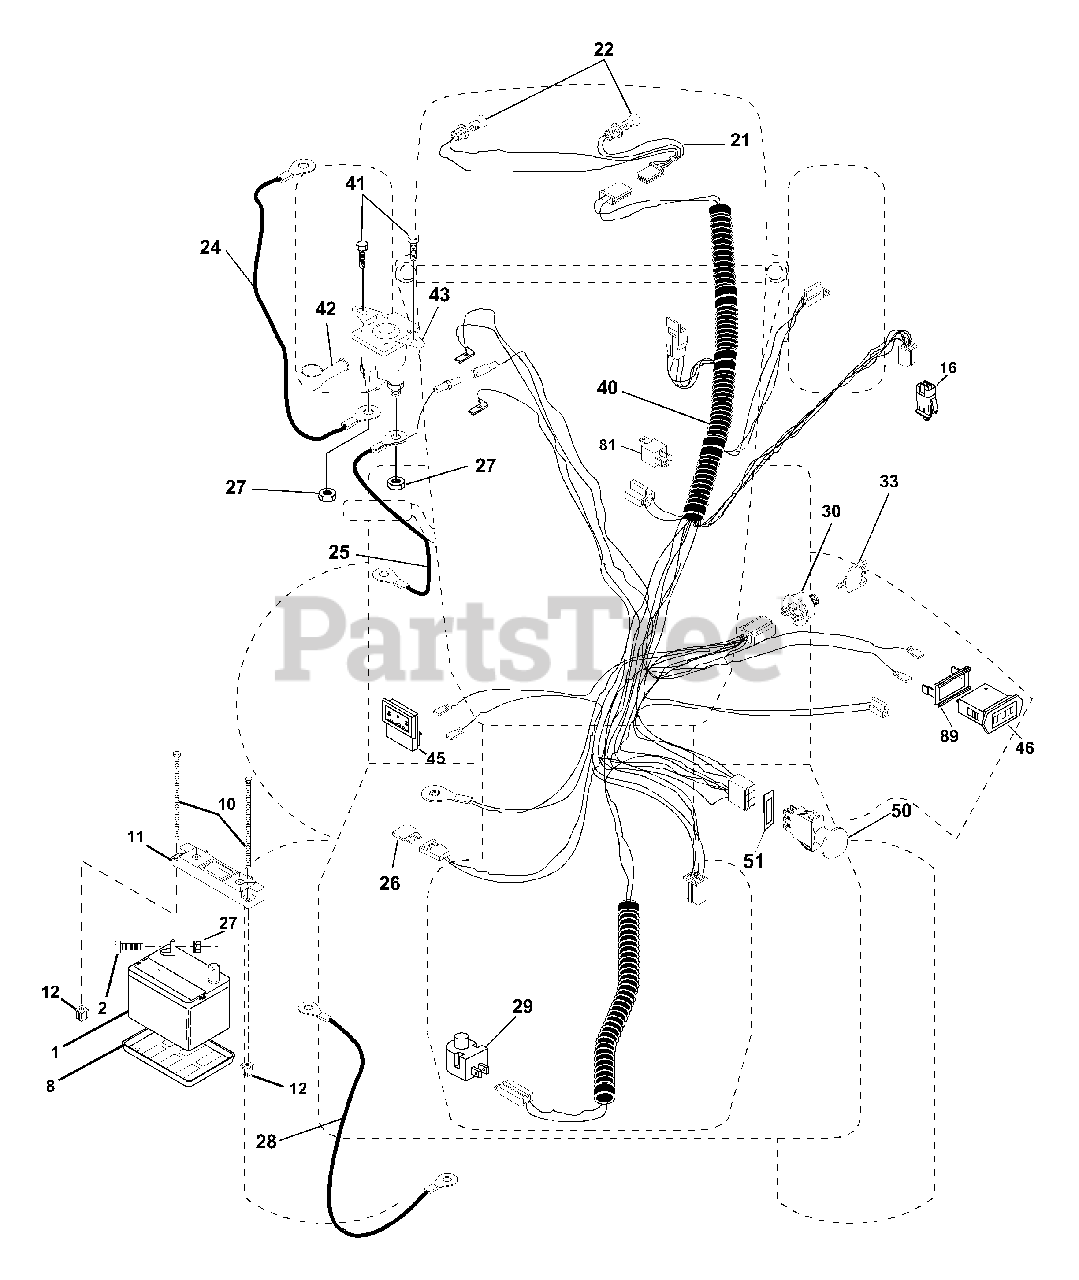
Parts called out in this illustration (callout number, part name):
1	Battery
2	Bolt Hex Head 1/4-20 x 3/4
8	Tray, Battery
10	Bolt, Btr Frt 1/4-20 x 7-1/2 Zinc
11	Holddown Battery Front Mount
12	Nut Push Nylon 1/4" Battery Frt.
16	Switch Interlock Push-In
21	Harness Socket Light w/4152J
22	Bulb Light
24	Cable, Starter
25	Cable, Battery
27	Nut Keps Hex 1/4-20 UNC
28	Cable, Ground
29	Switch, Plunger
30	Switch, Ign
40	Harness Ign.
41	Screw 1/4-20 x 1/2
42	Cover, Terminal Red
43	Solenoid
45	Ammeter Rectangular
46	Meter Hour Snap-In
50	Switch, PTO
51	Ring Retainer PTO
62	Bulb, Light Pkg.
81	Relay Asm.
89	Bracket Snap-In Hourmeter
